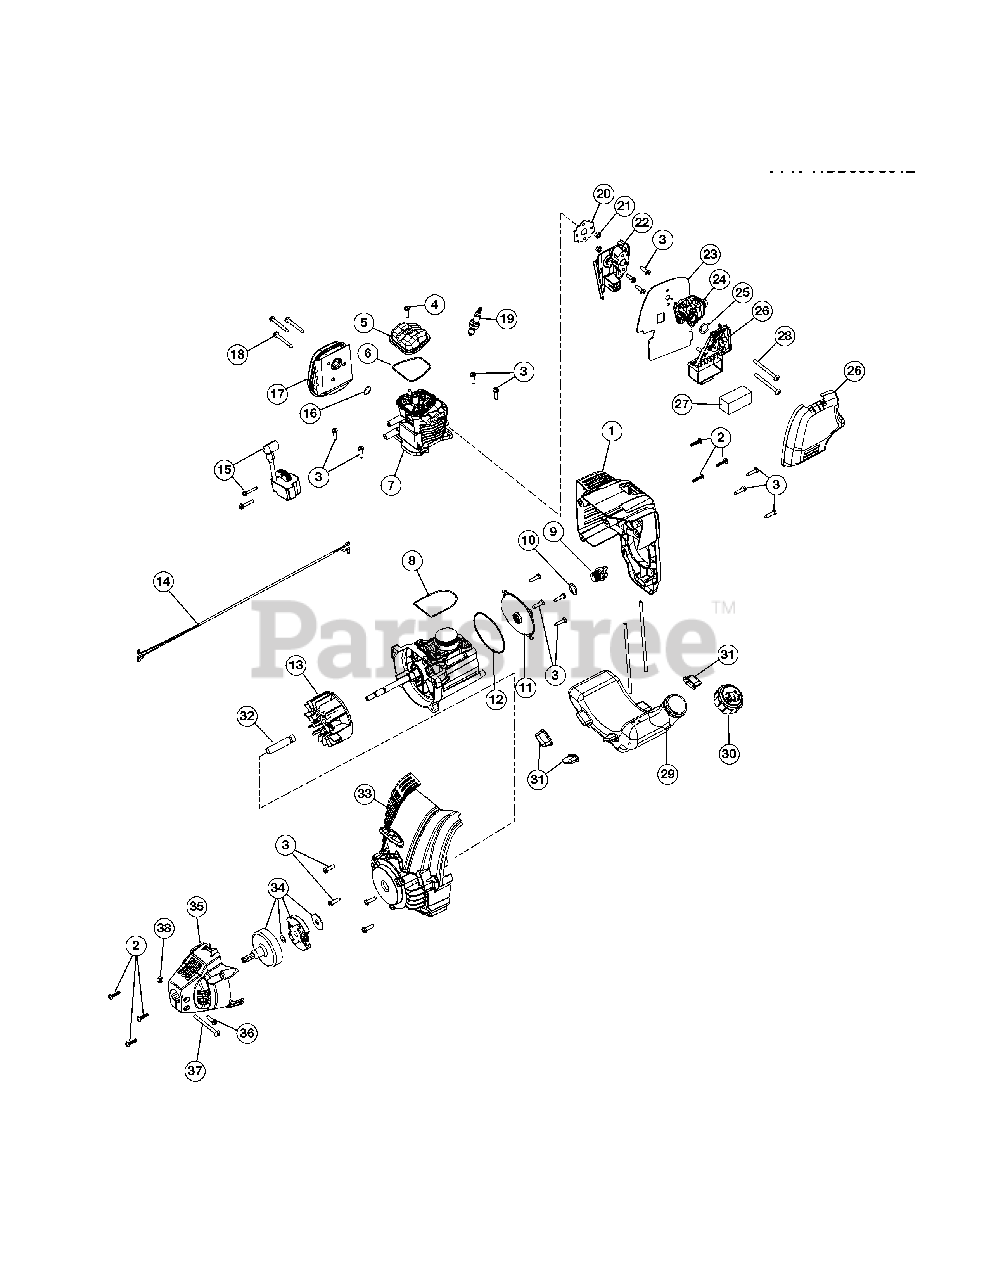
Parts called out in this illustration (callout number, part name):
1	Engine Cover Assembly
2	Cover Screw
3	Housing Screw
4	Rocker Cover Screw
5	Rocker Cover
6	Rocker Cover O-Ring
7	Cylinder Assembly
8	Cylinder O-Ring
9	Oil Plug
10	Oil Plug O-Ring
11	Crankcase Cover
12	Crankcase Cover O-ring
13	Flywheel Assembly
14	Lead Wires
15	Module Assembly
16	Muffler Gasket
17	Muffler Assembly
18	Muffler Screw
19	Spark Plug
20	Insulator Gasket
23	Carburetor Gasket
24	Carburetor
26	Air Cleaner Cover Assembly
27	Air Filter
29	Fuel Tank Assembly w/Fuel Lines
31	Fuel Tank Pads
33	Starter Housing Assembly
34	Clutch Assembly
35	Clutch Cover
36	Anti-Rotation Screw
37	Clamp Screw
